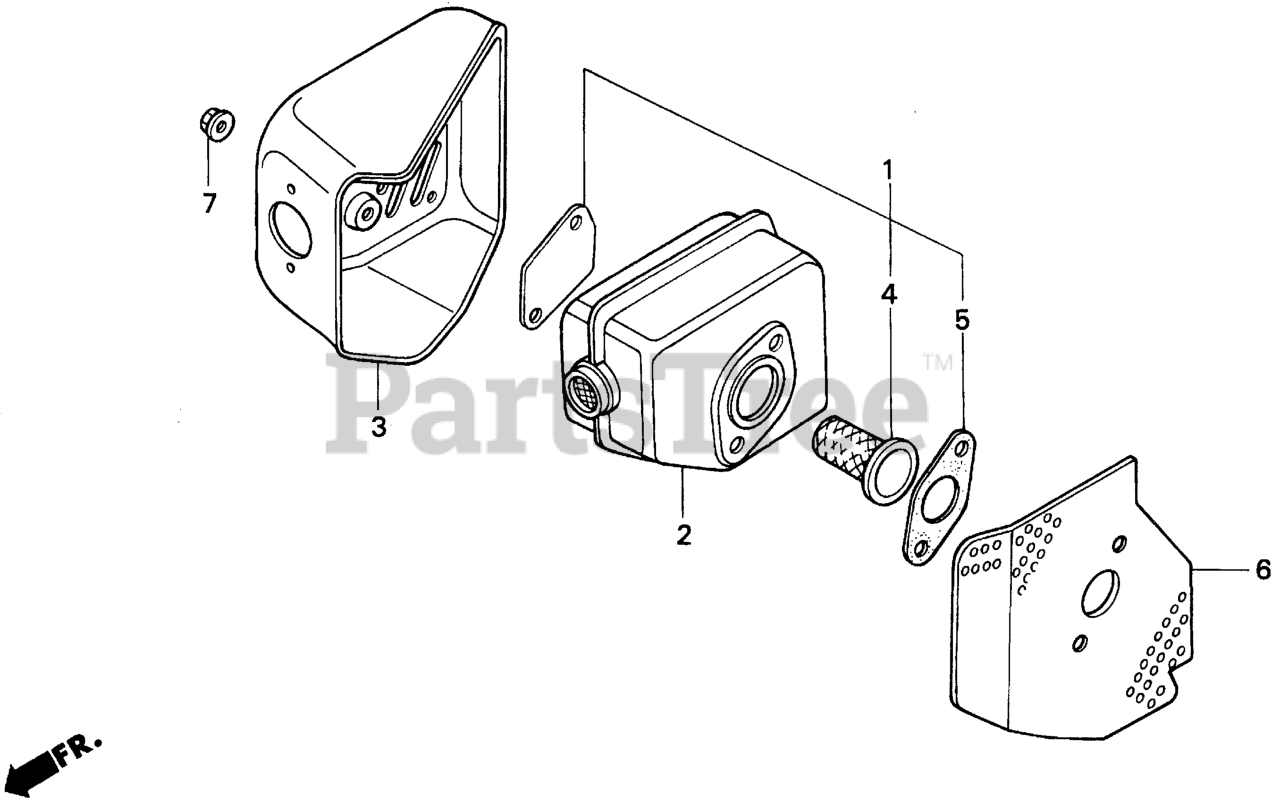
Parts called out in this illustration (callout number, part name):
1	ARRESTER KIT, SPARK
2	MUFFLER
3	PROTECTOR, MUFFLER
4	ARRESTER KIT, SPARK
5	GASKET, MUFFLER
6	GASKET, MUFFLER
7	NUT, SELF-LOCK (6MM)
